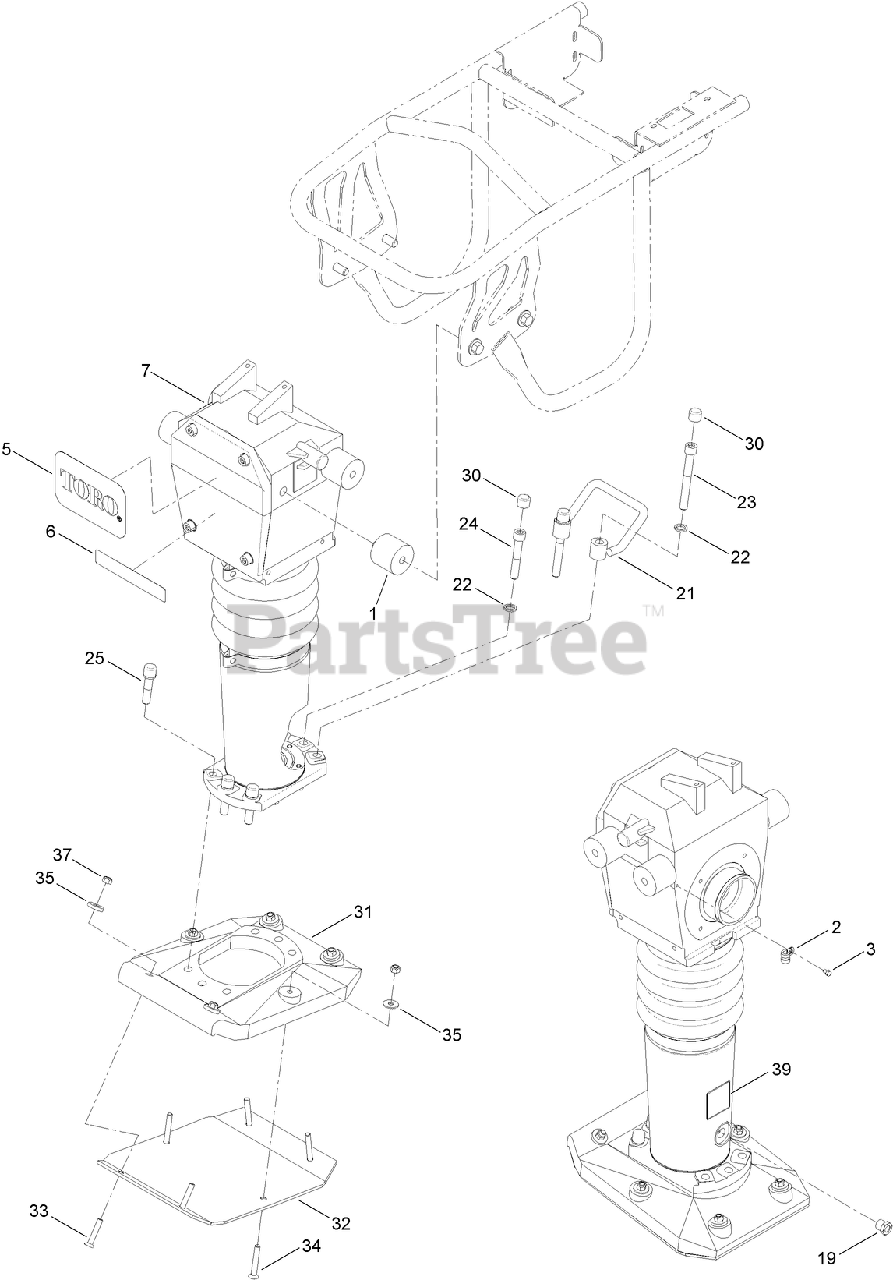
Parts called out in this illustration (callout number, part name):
1	MOUNT-SHOCK
2	CLAMP
3	SCREW-HH
7	RAMMER ASM
19	PLUG-SIGHT, OIL
21	GRIP-LIFTING
22	WASHER-LOCK
23	SCREW-HSH
24	SCREW-HSH
25	SCREW-HSH
30	CAP-PLASTIC
31	SHOE-PLASTIC, LIGHT
32	PLATE-SHOE
33	SCREW
34	SCREW-HSFH
35	WASHER-FLAT
37	NUT-LOCK, NI
39	DECAL-OIL LEVEL
